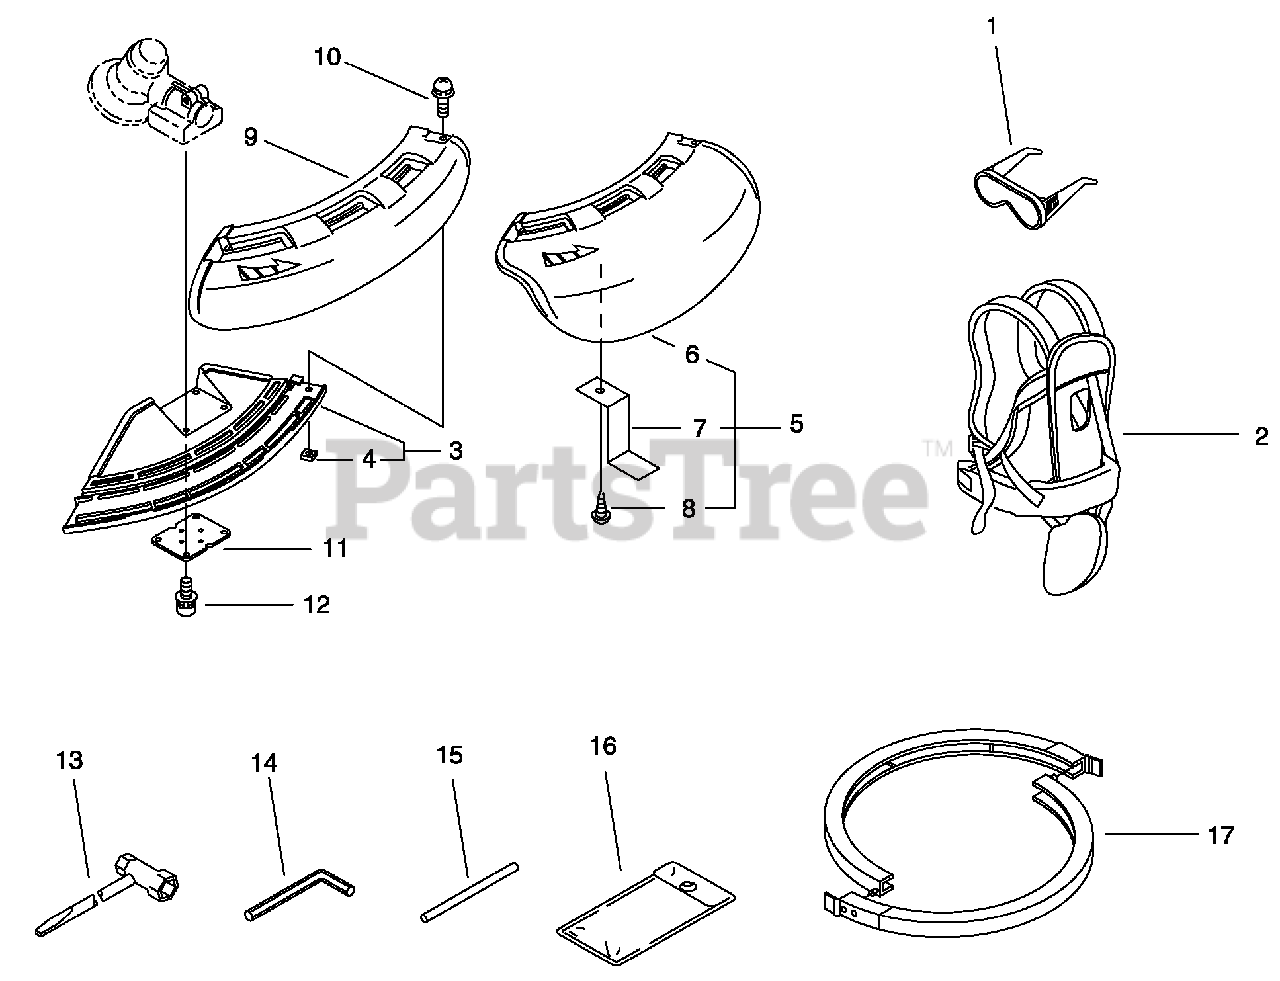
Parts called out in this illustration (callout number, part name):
1	GOGGLES
2	HARNESS ASSY
3	ADAPTOR, DEBRIS SHIELD
4	NUT - 5 -- SQUARE
5	DEBRIS SHIELD KIT - TRIMMER
6	SHIELD, DEBRIS - TRIMMER
7	KNIFE, TRIMMER LINE
8	SCREW - 5X12
9	SHIELD, DEBRIS - BLADE
10	SCREW - 5X22
11	BRACKET, SHIELD
12	BOLT - 5X25
13	T-WRENCH - 17X19mm
14	HEX KEY - 4mm
15	ROD, LOCKING - 5X120mm
16	BAG, TOOL
